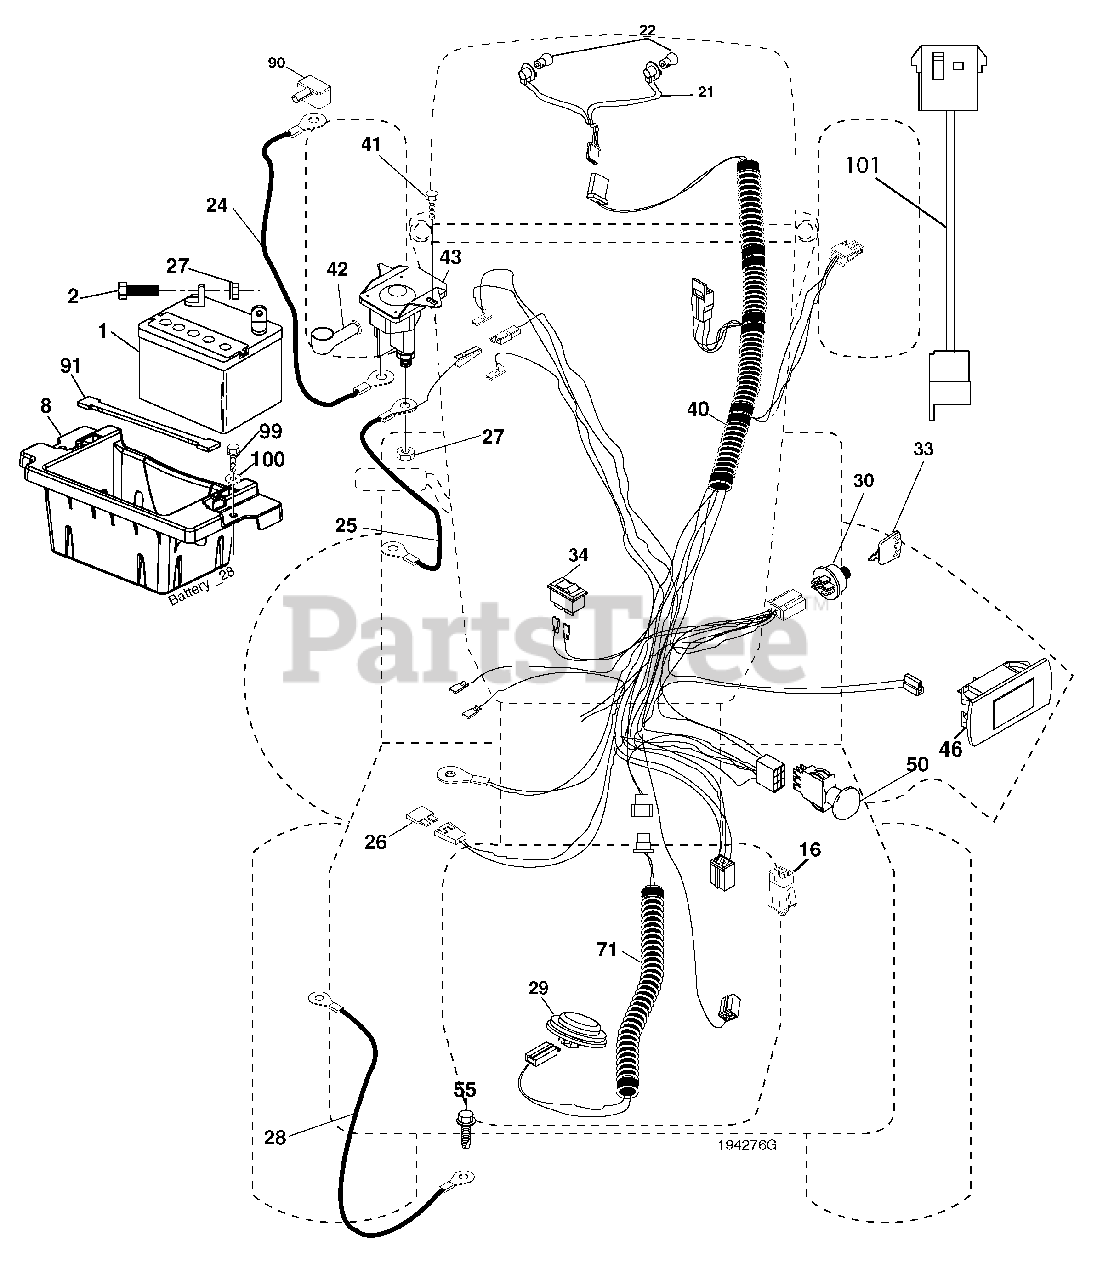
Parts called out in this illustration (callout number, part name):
1	Battery
2	Bolt Hex Head 1/4-20 x 3/4
8	Box Battery
16	Switch Interlock Push-In
21	Harness Socket Light W/4152J
22	Bulb Light
24	Cable Battery
25	Cable Starter
26	Fuse
27	Nut Keps Hex 1/4-20 unc
28	Cable, Ground
29	Switch, Seat
30	Switch, Ign
33	Key, Ignition
34	Switch Light / Reset
40	Harness Ign. Dash
41	Screw Thd Cut 1/4-20 x 1/2
42	Cover, Terminal
43	Solenoid
46	Gauge Hourmeter
50	Switch PTO
55	Screw Thdrol 5/16-18 x 3/4 TYTT
71	Harness Chassis
90	Cover Terminal Battery
91	Strap Battery Mount Front
99	Screw Hexwsh Thdrol 1/4-20 x 3/4
100	Washer 9/32 x 7/8 x 16 Ga.
101	Pigtail
